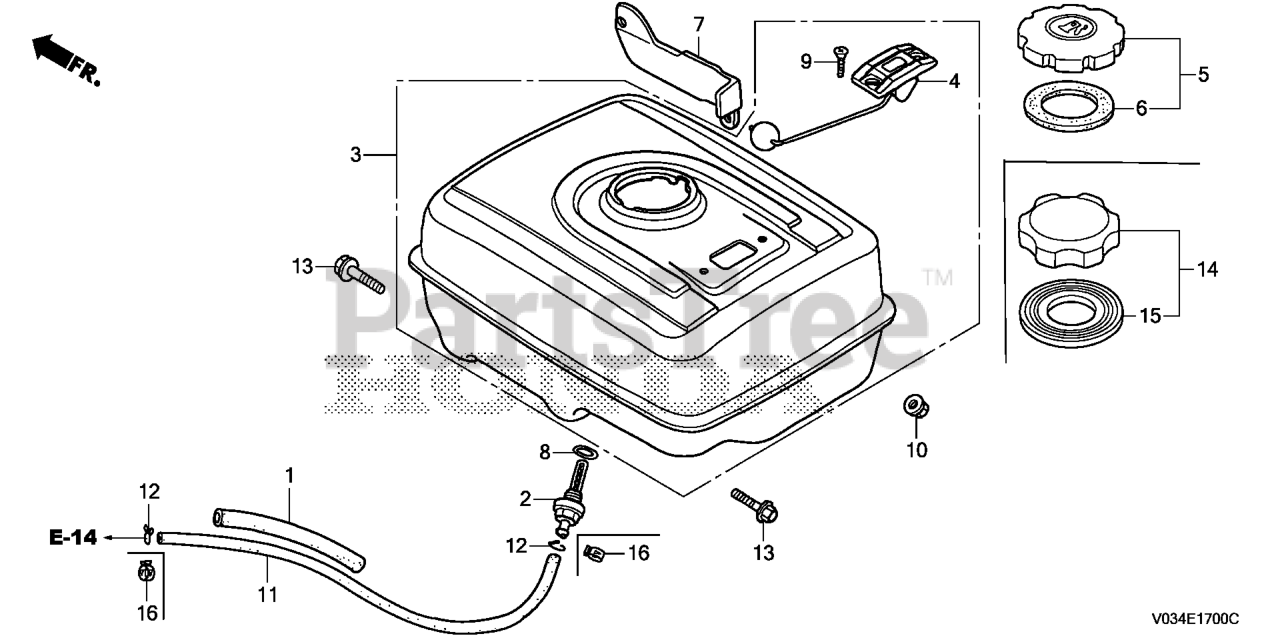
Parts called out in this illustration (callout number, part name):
1	RUBBER, SUPPORTER (107MM)
2	JOINT, FUEL TANK
3	TANK ASSY., FUEL *R280* (GAUGE) (POWER RED)
4	GAUGE ASSY., FUEL
5	CAP, FUEL FILLER (BLACK) Use up to Engine SN 2115700.
5	CAP, FUEL FILLER (CHROME PLATED)
6	GASKET, FUEL FILLER CAP (39X58X3) (NOT AVAILABLE)
6	GASKET, FUEL FILLER CAP Use from Engine SN 1543258.
6	GASKET, FUEL FILLER CAP (39X58X3)
7	COVER, SNOW PLATE
8	O-RING (14MM) (ARAI) Use up to Engine SN 2949254.
9	SCREW, FLAT (5X10)
10	NUT, FLANGE (8MM)
11	BULK HOSE, FUEL (4.5X3000) (Honda Code 5137104). (4.5X140)
12	CLIP, TUBE (B8)
13	BOLT, FLANGE (8X28)
